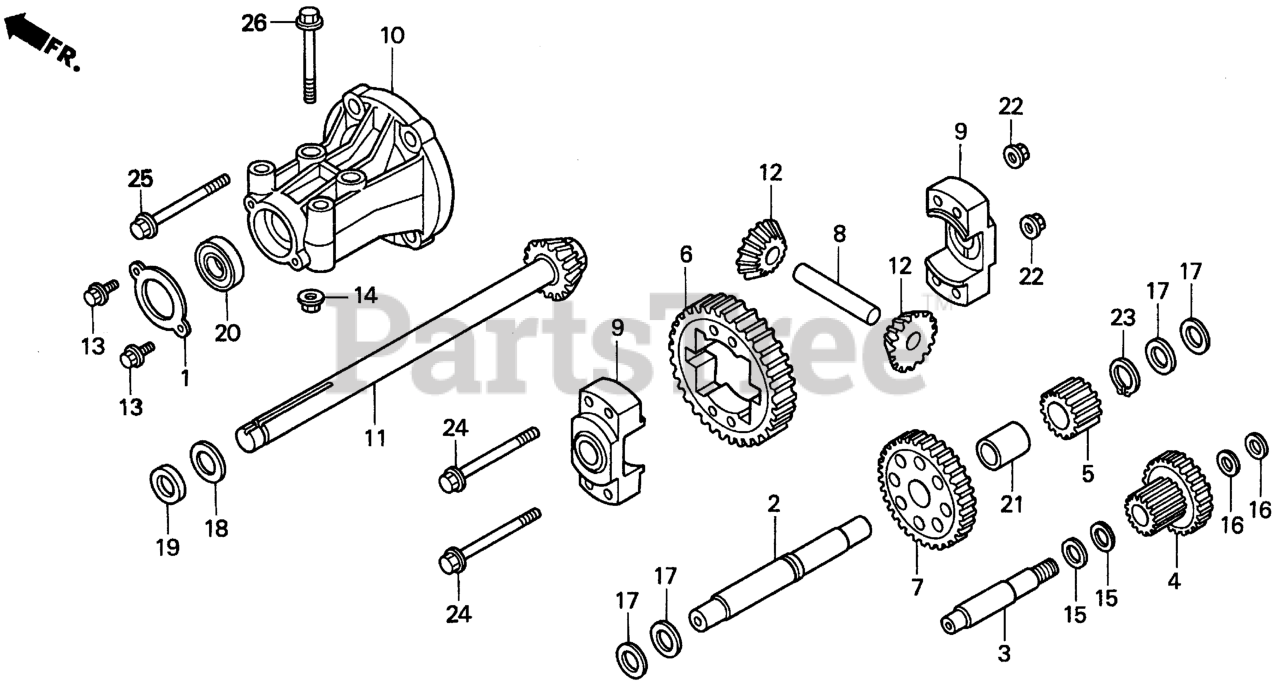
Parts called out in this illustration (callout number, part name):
1	PLATE, BEARING HOLDER
2	COUNTERSHAFT
3	SHAFT, IDLER
4	GEAR, IDLE
5	GEAR, FINAL DRIVE
6	GEAR, FINAL DRIVEN
7	GEAR, COUNTERSHAFT DRIVEN
8	SHAFT, PINION
9	SUPPORT, FINAL DRIVEN GEAR
10	HOUSING, R. RR. AXLE
11	SHAFT, AXLE
12	GEAR, PINION
13	BOLT, FLANGE (6X14)
14	NUT, FLANGE (8MM)
15	WASHER, THRUST (15MM)
16	WASHER, THRUST (12MM)
17	WASHER, THRUST (18MM)
18	WASHER, THRUST (20MM)
19	WASHER, THRUST (20MM)
20	BEARING, RADIAL BALL (1630)
21	BUSH (13X16.2X25)
22	NUT, FLANGE (8MM)
23	CIRCLIP (OUTER) (22MM)
24	BOLT, FLANGE (8X85)
25	BOLT, FLANGE (10X25)
26	BOLT, FLANGE (8X70)
